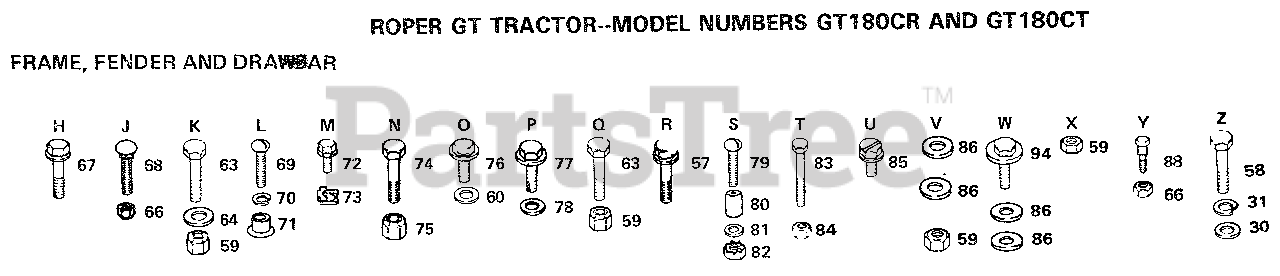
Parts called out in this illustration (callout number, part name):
30	WASHER
31	LOCKWASHER
57	SCREW
60	WASHER PM
63	BOLT
64	WASHER
68	BOLT
69	SCREW
70	LOCKWASHER
71	WELDNUT
73	"""J"" FASTENER LT"
74	BOLT T
76	SCREW HEX CRT
77	SCREW
78	WASHER M
79	SCREW
80	SPACER LT
81	WASHER
83	BOLT
84	NUT GTV
85	SCREW LT
86	WASHER
94	SCREW GTV
